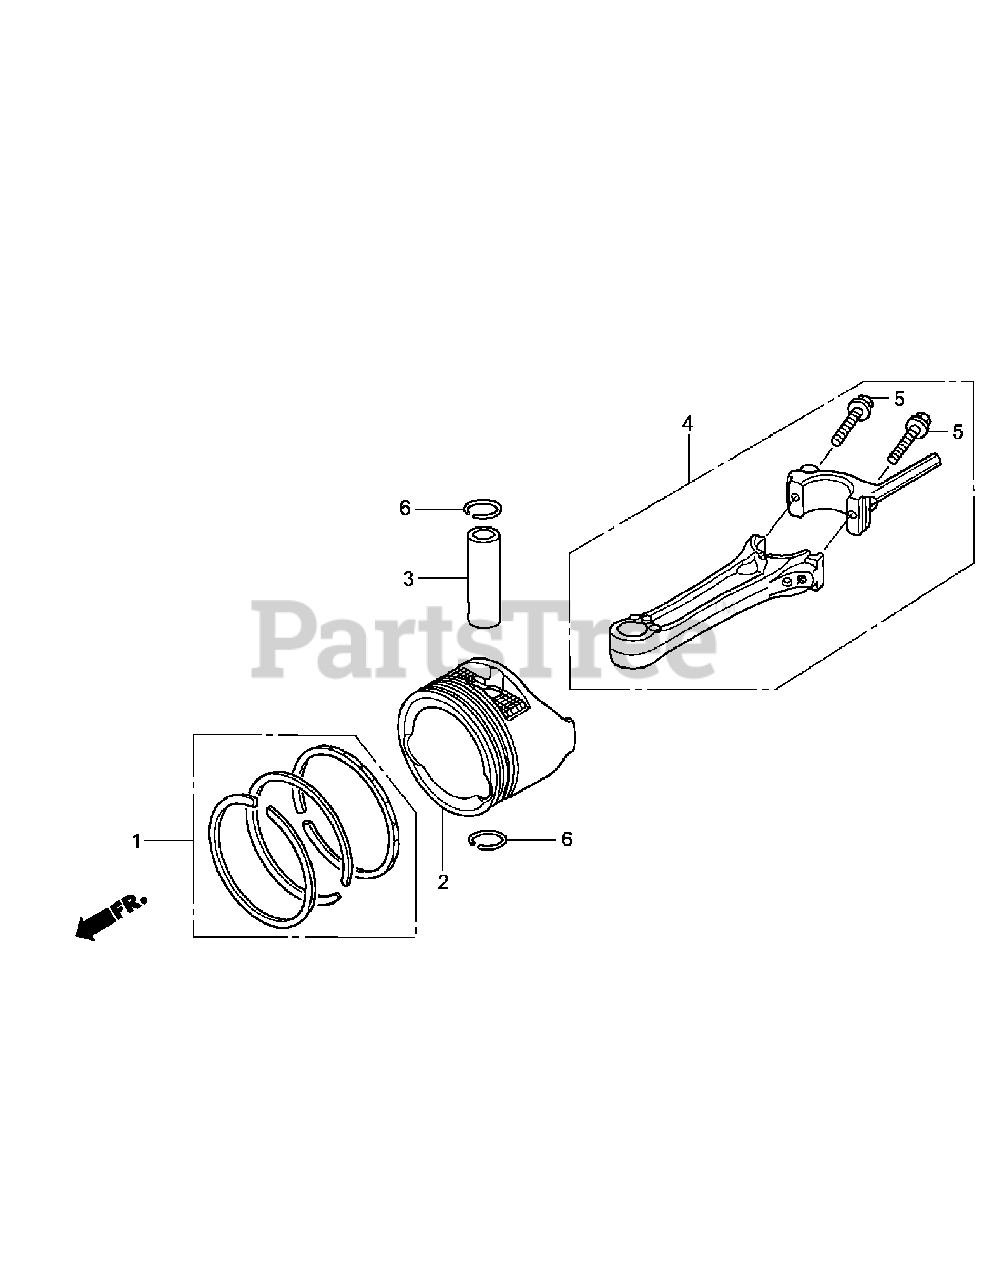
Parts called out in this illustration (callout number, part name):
1	Ring Set, Piston (Std). (Teikoku)
2	Piston
3	Pin, Piston
4	Rod Assy., Connecting.
5	Bolt, Connecting Rod.
6	Clip, Piston Pin (13mm)
